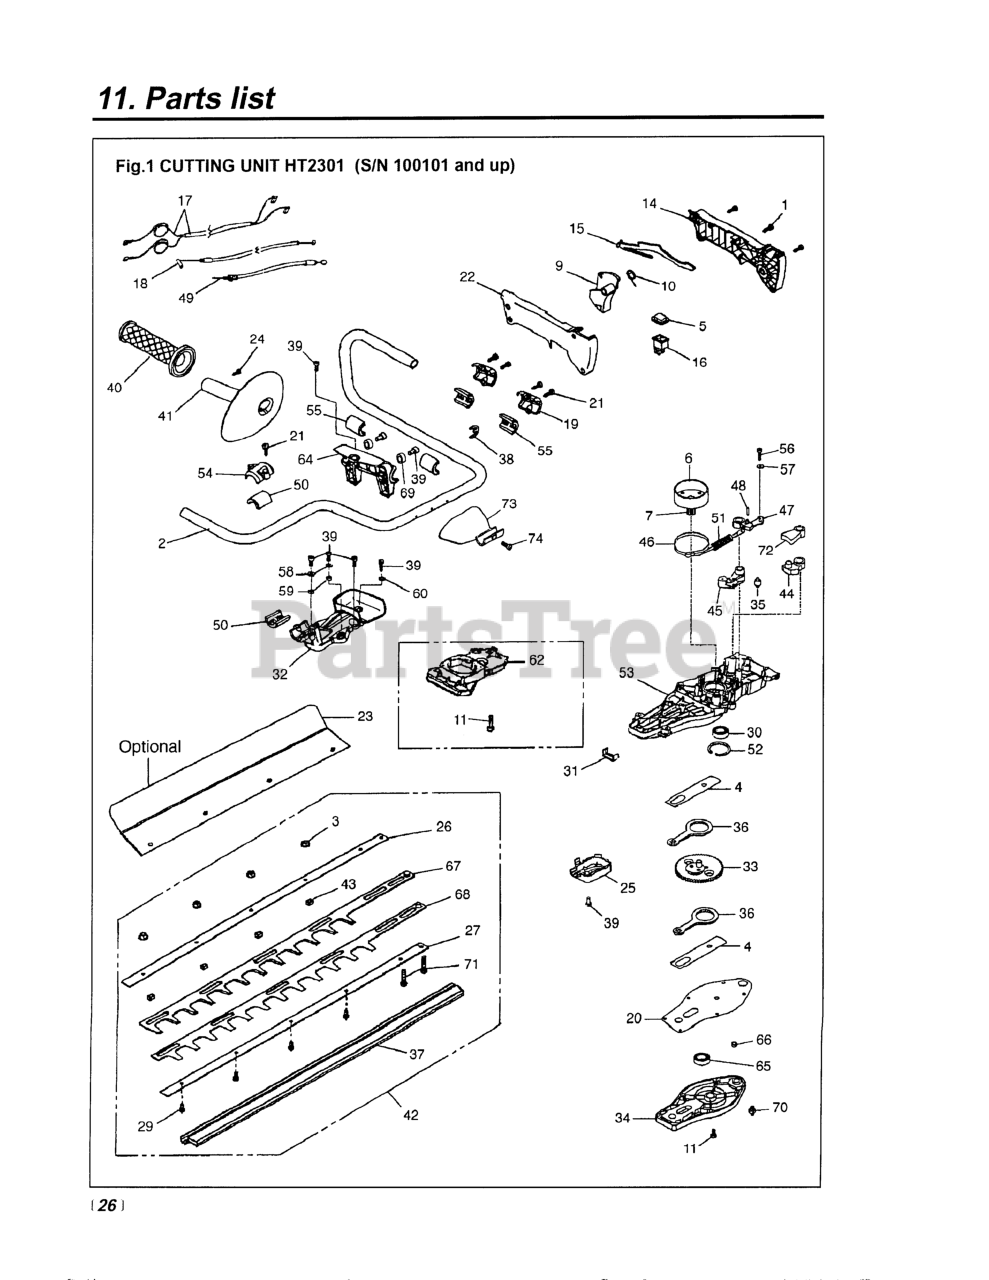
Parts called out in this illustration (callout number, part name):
1	SCREW (HANDLE)
3	NUT
4	PLATE
5	GUARD, SWITCH
6	CLUTCH DRUM
7	DRIVE GEAR (USE T4504-13110)
9	LEVER, THROTTLE
10	SPRING
11	SCREW TORX, M5X22
15	LEVER
16	SWITCH (RPLS 2317011A)
17	CABLE
18	CABLE, THROTTLE
20	GASKET
21	SCREW (HANDLE)
23	DEFLECTOR
26	SUPPORT, UPPER
27	SUPPORT, LOWER
29	SCREW
30	BEARING
32	SUPPORT
34	COVER
35	ROLLER
37	GUARD, BLADE
39	SCREW
42	BLADE ASSY (RPLS 58040094)
43	SPACER
44	CAM, BRAKE
45	LEVER
46	BAND, BRAKE
47	LEVER, BAND
48	PIN
49	THROTTLE CABLE
51	SPRING
52	RING, SNAP
53	CASE, GEAR (RPLS 58042021)
56	SCREW
57	WASHER
60	BUSHING
62	COVER, GEAR
64	SUPPORT
65	BEARING
66	GREASE NIPPLE
67	BLADE, UPPER
68	BLADE, LOWER
70	GREASE NIPPLE
71	SCREW (BLADE)
72	LEVER
